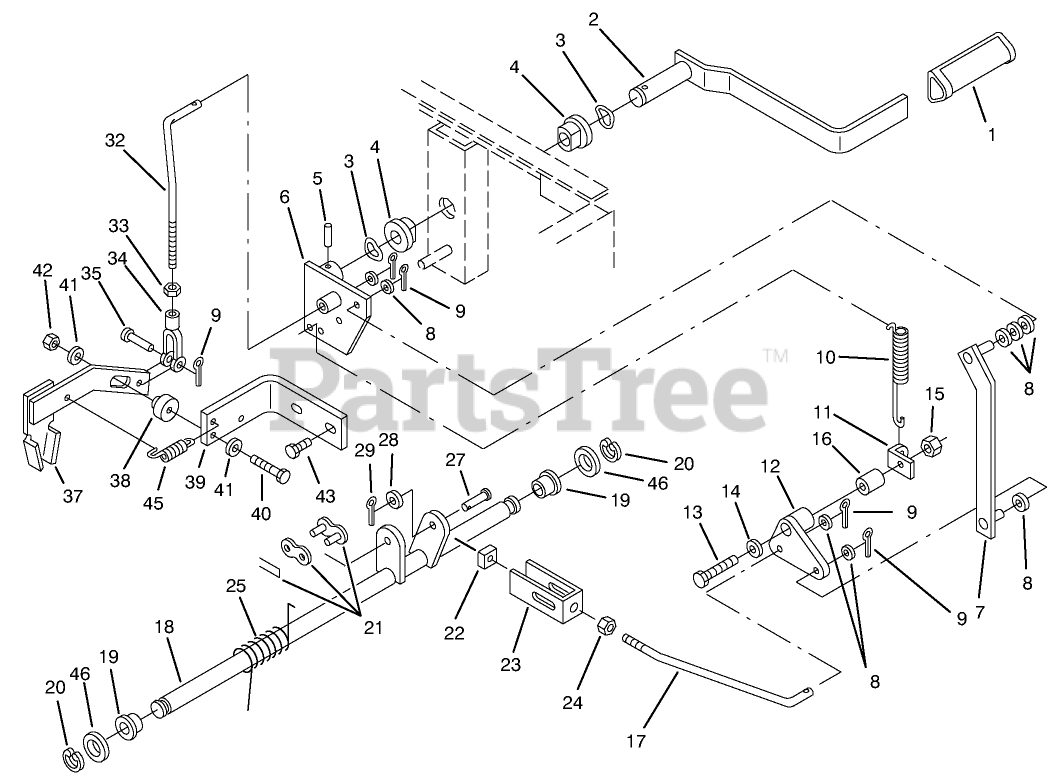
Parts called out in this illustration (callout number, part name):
1	GRIP-PARKING BRAKE
2	Brake Lever
3	WASHER-BOWED
4	BEARING-FLANGED
5	PIN-SPIRAL
6	Arm
7	ASSY-BRAKE BAR UP
8	WASHER-PLAIN
9	PIN-COTTER
10	SPRING-EXTENSION
11	CLIP - SPRING
12	WLMNT-BRAKE PIVOT
13	SCREW-HH
14	WASHER-FLAT
15	NUT-LOCK, NI
16	SPACER
18	Shaft-Brake
19	BUSHING
20	Ring-Snap
21	CONNECTING LINK
22	NUT 5/16-18 SQ
23	YOKE-ADJUSTER
24	NUT-HEX
25	SPRING-TORSION
28	WASHER-FLAT
29	PIN-COTTER
32	ROD-NEUTRAL LOCK
33	NUT-JAM
34	YOKE
37	Lock-Neutral
38	SPACER
39	Bracket-Support
40	SCREW-HH
41	WASHER-FLAT
42	NUT-LOCK, NI
43	SCREW-HWHTF
45	SPRING-EXTENSION
46	WASHER-FLAT
